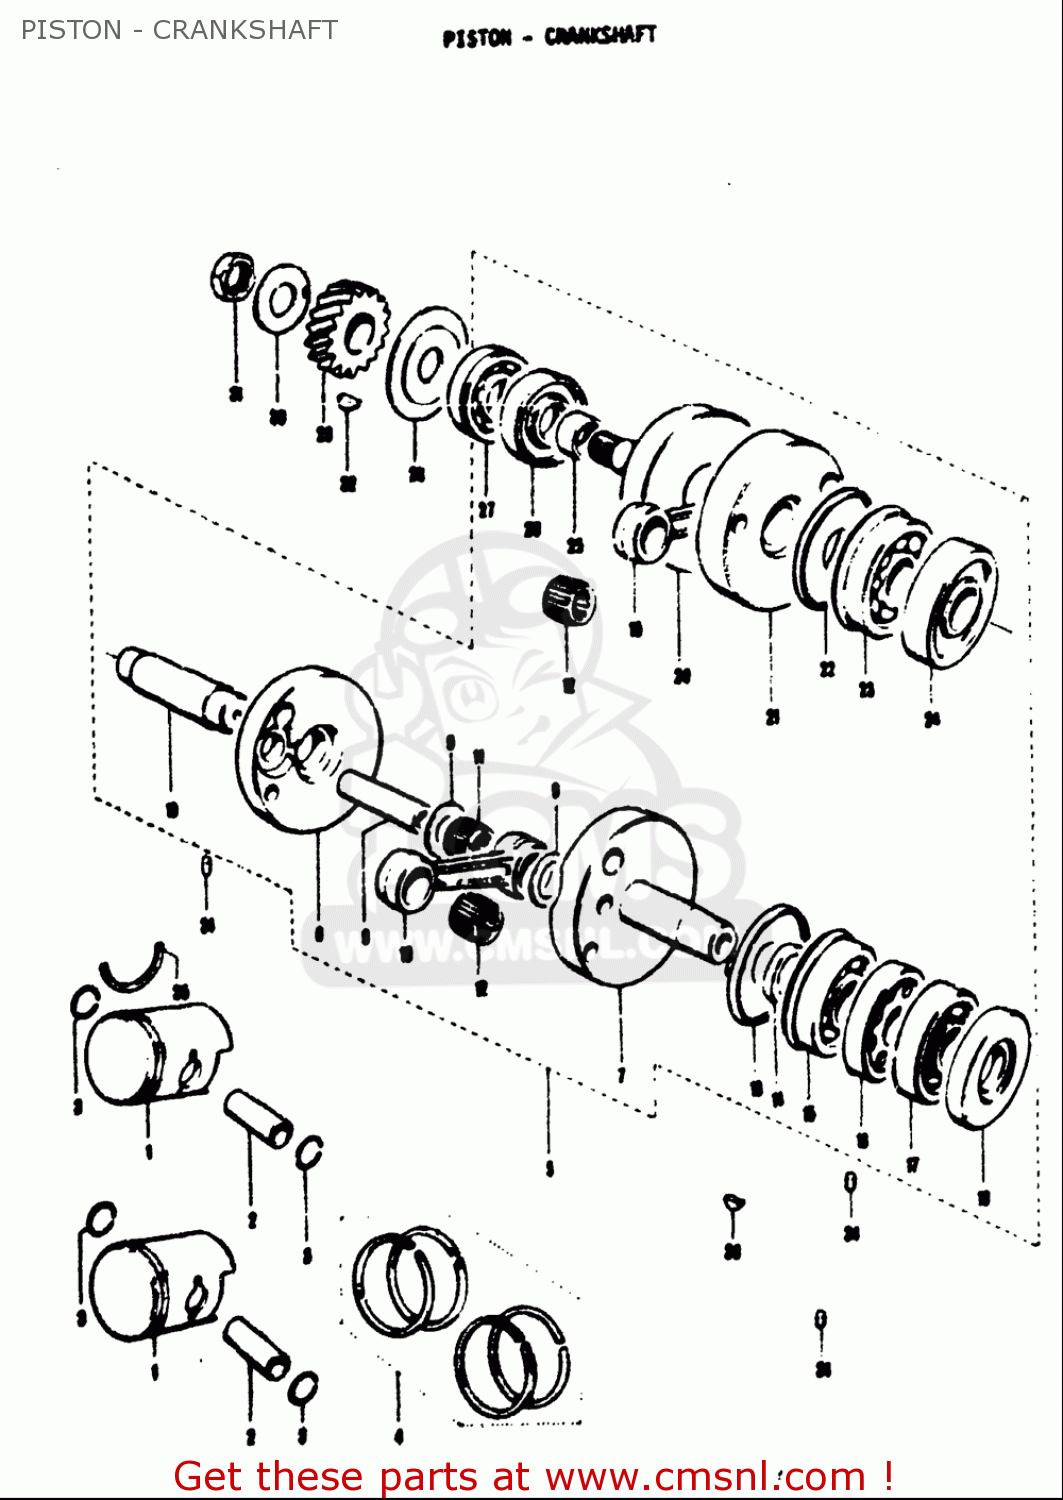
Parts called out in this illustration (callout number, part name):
2	PIN,PISTON
3	RING,SNAP
4	RING SET,PISTON
9	WASHER(17X29X1)
10	ROD,CONNECTING
11	BEARING(17X23X14)
12	BEARING(12X16X16)
14	SPACER(20X28X4.5)
18	SEAL,OIL(19.6X37X8)
25	SPACER(20X26X9)
31	NUT
32	KEY
33	KEY
34	ROLLER(4X13.8)
35	C RING
